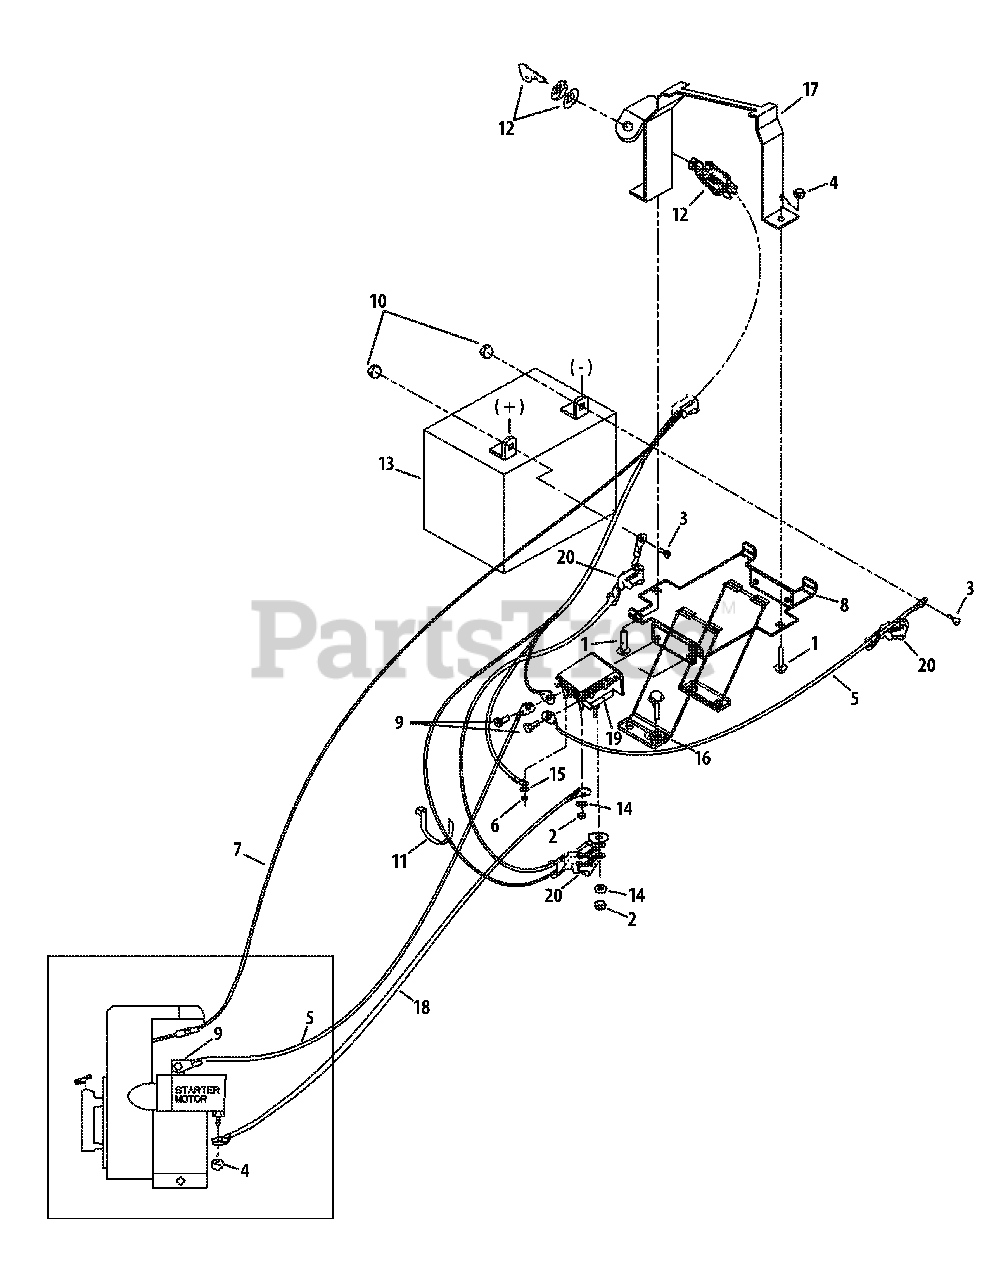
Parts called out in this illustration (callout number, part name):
1	Carriage Screw 1/4-20 x 1.25
2	Hex Nut 5/16-24
3	Flange Screw 1/4-20 x .625
4	Hex Locknut 1/4-20
5	Cable (Ground Wire)
6	Hexlock Washer Nut, 10-32
7	Electric Start Harness
8	Battery Bracket Assembly
9	Self-tapping Screw 1/4-20 x .5
10	Hex Nut 1/4-20
11	Cable Tie
12	Ignition Switch
13	Battery 270 CCA
14	Lock Washer 5/16
15	Lock Washer #10
16	External Lock Washer 5/16
17	Keyswitch Clamp
18	Cable (Solenoid to Starter Motor)
19	Solenoid
20	Insulating Boot
